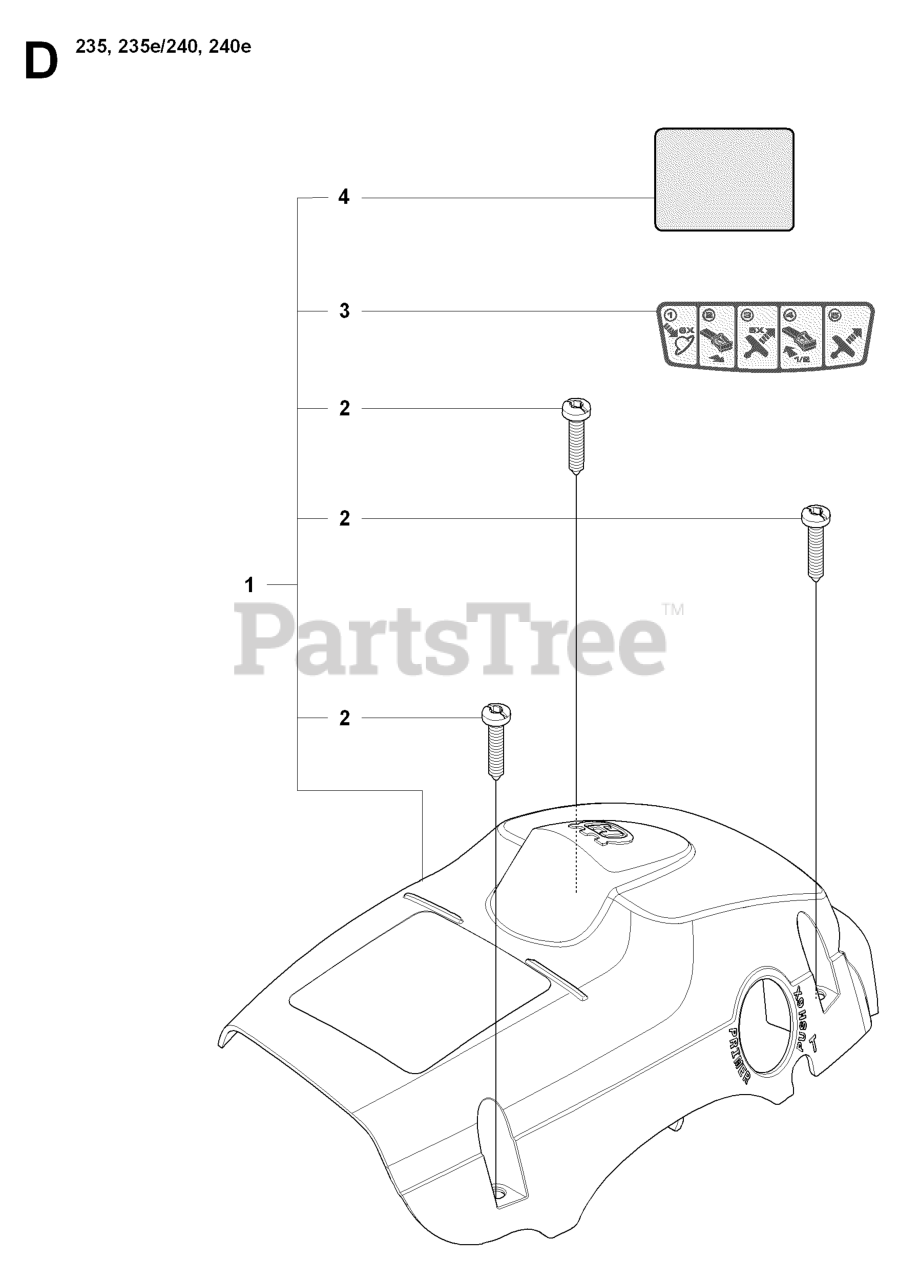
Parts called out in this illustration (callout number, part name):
1	CYLINDER SHIELD
2	SCREW
4	WARNING SIGN
